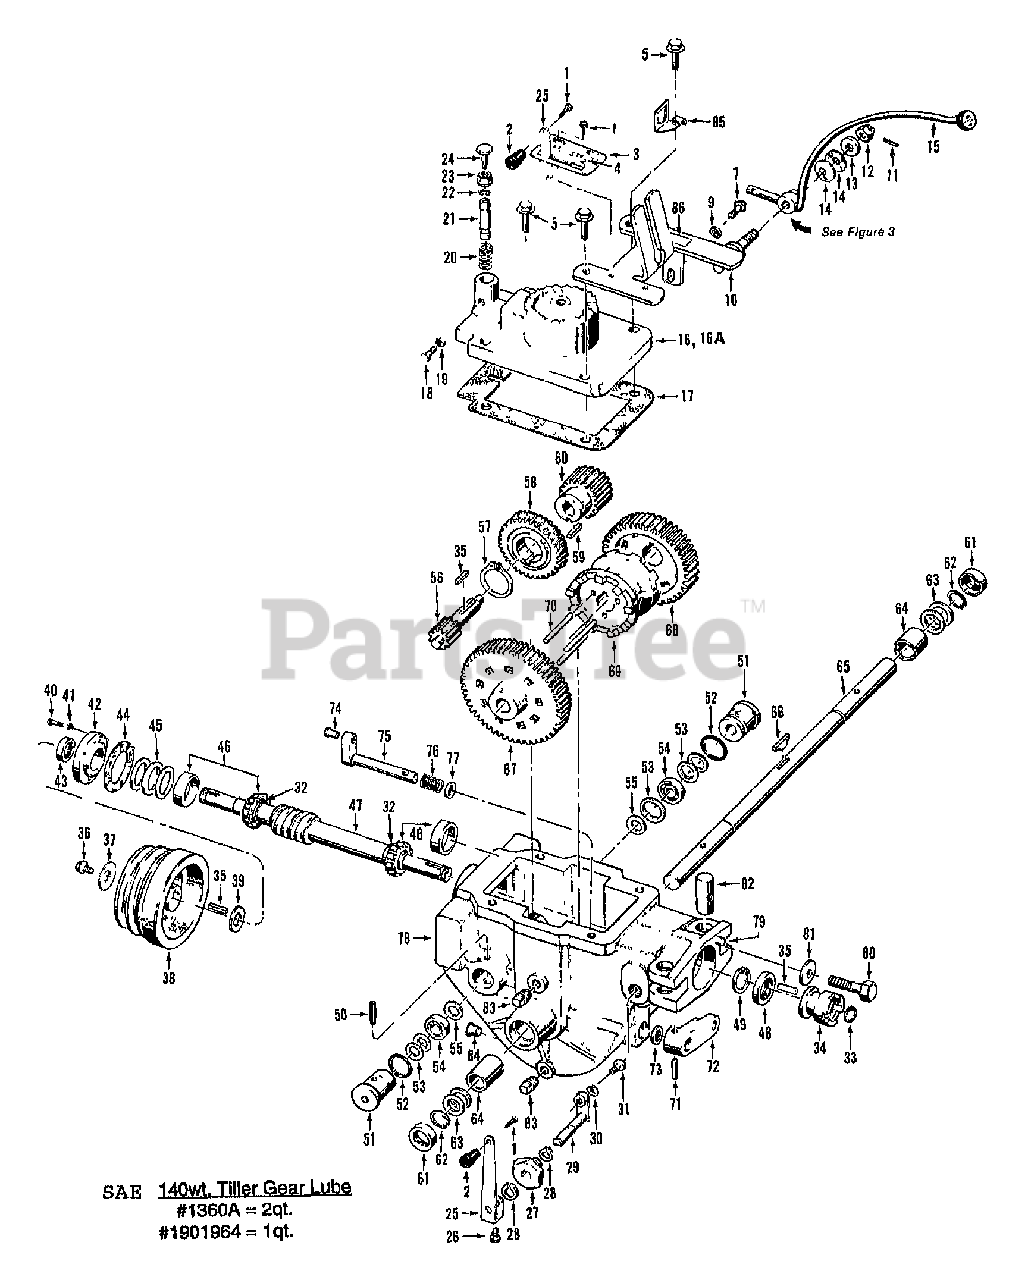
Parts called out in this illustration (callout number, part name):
1	SCR 10-32
2	KNOB-TAPERED
3	PLATE-TINE ENGAGE W/DECAL
4	DECAL-TINE ENGAGE
5	SCR-HFLK 3/8-16X1.50
7	SCR-HFLK 5/16-18X.75 ZP
9	WASHER-FLAT 5/16 SAE
10	BRKT-H HOOD 2149
11	PIN-SPRING .125 X 1
12	NUT
12	NUT-HEX 1/2-20 CALL TECH. SERVICE DEPT. FOR TIGHTENING INSTRUCTIONS.
13	WASHER-# SHOULDER ZP (SHOULDER FACES DISC WASHERS)
14	WASHER-# 1.97X1X.118 (CONCAVE SURFACES FACE EACH OTHER)
15	LEVER
16	COVER-TRANS RED 2523
16A	ASSM-TRANS COVER OPC
17	GASKET-TRANS COVER
18	SCR-HH 5/16-18X1.0 G5 ZP (REMOVE WITH CARE) SEE REF.#'S 20 & 21
19	NUT-HEX 5/16-18 ZP
20	SPRING-REV PLUNGER ZP (REMOVE WITH CARE)
21	ASSM-NEUTRAL PLUNGER (REMOVE WITH CARE) INCLUDES #9504 CLIP RING(REF.#22)
22	RING-KLIP EXT .594 ID ZP
23	NUT-HFLK 3/8-16 ZP
24	SCR 3/8-16X1.5 UNC-2AG
25	LEVER-ECCENTRIC RED (ALSO SEE REF.#'S 1,2 3 AND 4 LISTED ABOVE)
26	SCR-HH 1/4-20X.5 GR5 YEL
27	BUSHING-.87X.5X.62 ECC
28	RING-RETAINING 5100-50
29	SHAFT-WELD ECCENTRIC
30	WASHER-LK .25 HI-COLLAR
31	SCR-HXSKT 1/4-20X.38 G8
32	SHIM-1.0X.7656X.062 SHOULDER(DRIVE SHAFT)
33	RING-RETAIN EXT .707 ID
34	KIT-CLUTCH DOGS TILLER
35	KEY-.188 SQX1.0 (USED ON DRIVE SHAFT AND PINION SHAFT)
36	SCR-HH 5/16-24X.75 G5 ZP
37	WASHER-.827X.331X.098
38	PULLEY-TRANS MACH
39	WASHER-SHLDR HARDENED
40	SCR-HH 1/4-20X.75 G5 ZP
41	WASHER-LK .25 ZP
42	COVER-FRONT
43	SEAL-PINION SHAFT PT/85030/00
44	GASKET-BRG COVER
45	SHIM-1.75X1.5X.01
45	SHIM-1.75X1.5X.03
45	SHIM-1.75X1.5X.005
45	SHIM-1.75X1.5X.062
46	KIT-BRG CONE&RACE-DRIVESHAFT
47	KIT-WHEELDRIVE ROLL/WORM
48	SEAL-OIL DRIVESHAFT
49	RING-RETAINING 5000-181
50	PIN-SPIROL .25 X 2.0 (REF.#51)
51	PLUG-PINION BRG W/RING (REF.#52)
52	RING-O 1 ID
53	SHIM-1.234X1.015X.033
53	SHIM-1.234X1.015X.062
53	SHIM-1.234X1.015X.01
54	BRG-BALL (7 BALLS)
55	WASHER-# 1X.484X.06
56	GEAR-SPLINE 10 TEETH MACH (DRIVES SLOW SPEED WHEEL GEAR)
57	RING-RETAINING 5100-150
58	GEAR-WORM MACH
59	KEY
60	GEAR-SPUR 20 TEETH MACH (DRIVES FAST SPEED WHEEL GEAR)
61	SEAL-OIL WHEELSHAFT
62	RING-HEAVY EXT .906 ID
63	SHIM-1.375X1.015X.062
63	SHIM-1.375X1.015X.03
63	SHIM-1.375X1.015X.015
63	SHIM-1.375X1.015X.01
63	SHIM-1.375X1.015X.005
64	BUSHING-1.25X1.005X1.5
65	KIT-WHEELSHAFT
66	KEY-HI PRO .25X1.812
67	GEAR-SPUR 56 TEETH MACH
68	GEAR-SPUR 46 TEETH MACH
69	CLUTCH-MACH
70	PIN-CLUTCH .25 2.65
71	PIN-SPIROL .188 X 1.25
72	LEVER-ECC. #1029
73	SEAL-OIL ECCENTRIC
74	PIN-.375 X .72
75	SHAFT-ECCENTRIC HORSE TLR
76	SPRING .845 X 1.25
77	WASHER # .875 X .65 X .06
78	CASE-TRANS W/PIN
79	PIN-DRIVE .375X.75 ZP
80	SCR-HH 1/2-13X2.0 G5 ZP
81	WASHER-DISC SPRING
82	POST (TC) WITH THREADED HOLE FOR #9560 BOLT( REF.#80)
83	PLUG-PIPE 1/4 NPT
84	PLUG-CAP (RED)
85	CLIP-CONNECTOR (ALSO SEE PAGE 16)
86	DECAL-FWD INTERLOCK WIRE
